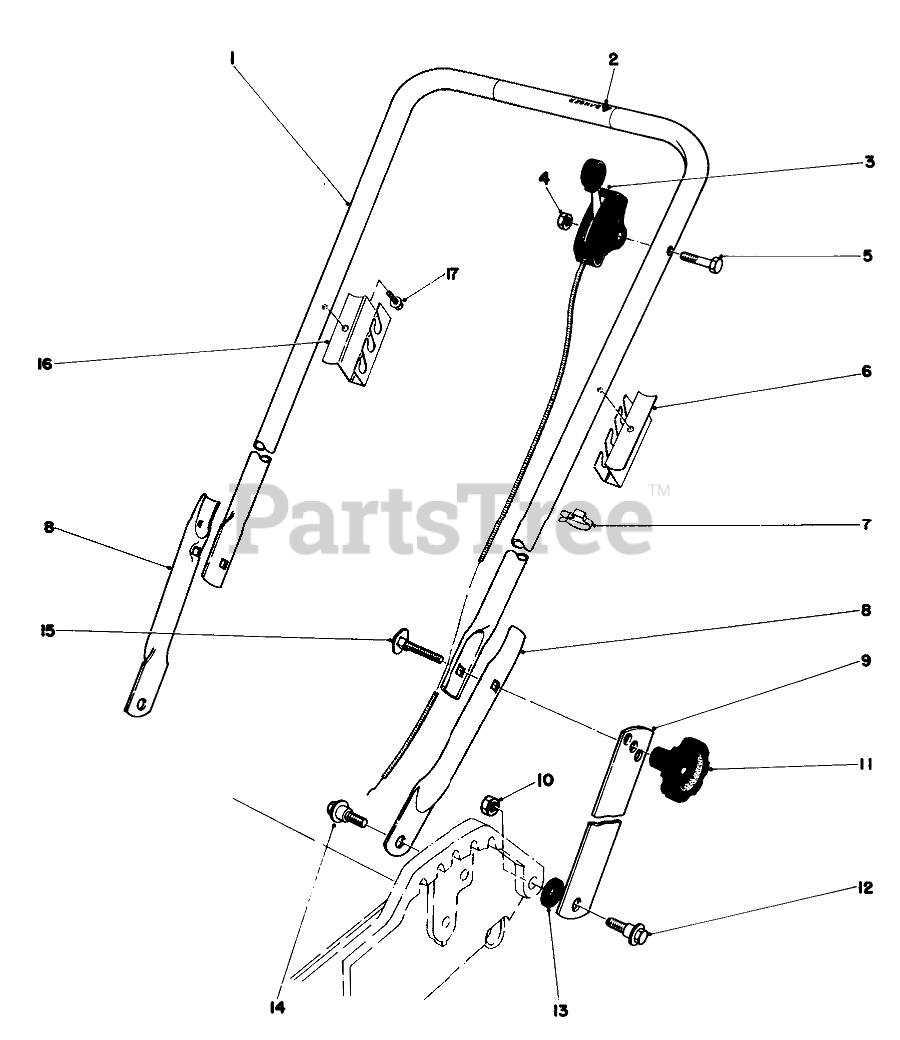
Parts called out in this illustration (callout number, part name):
1	Upper Handle (Incl. Ref. #2)
2	Decal
3	Throttle Control
4	NUT-LOCK
5	SCREW-HH
6	SUPPORT BAG LH
7	BOWDEN CLIP
8	Hand-Lower
9	18" HANDLE LATCH
10	Nut
12	SCREW-SHOULDER
13	HANDLE LATCH SPACER
14	SCREW-SHOULDER
15	SCREW-HANDLE
16	SUPPORT BAG RH
17	SCREW-HWHTF
